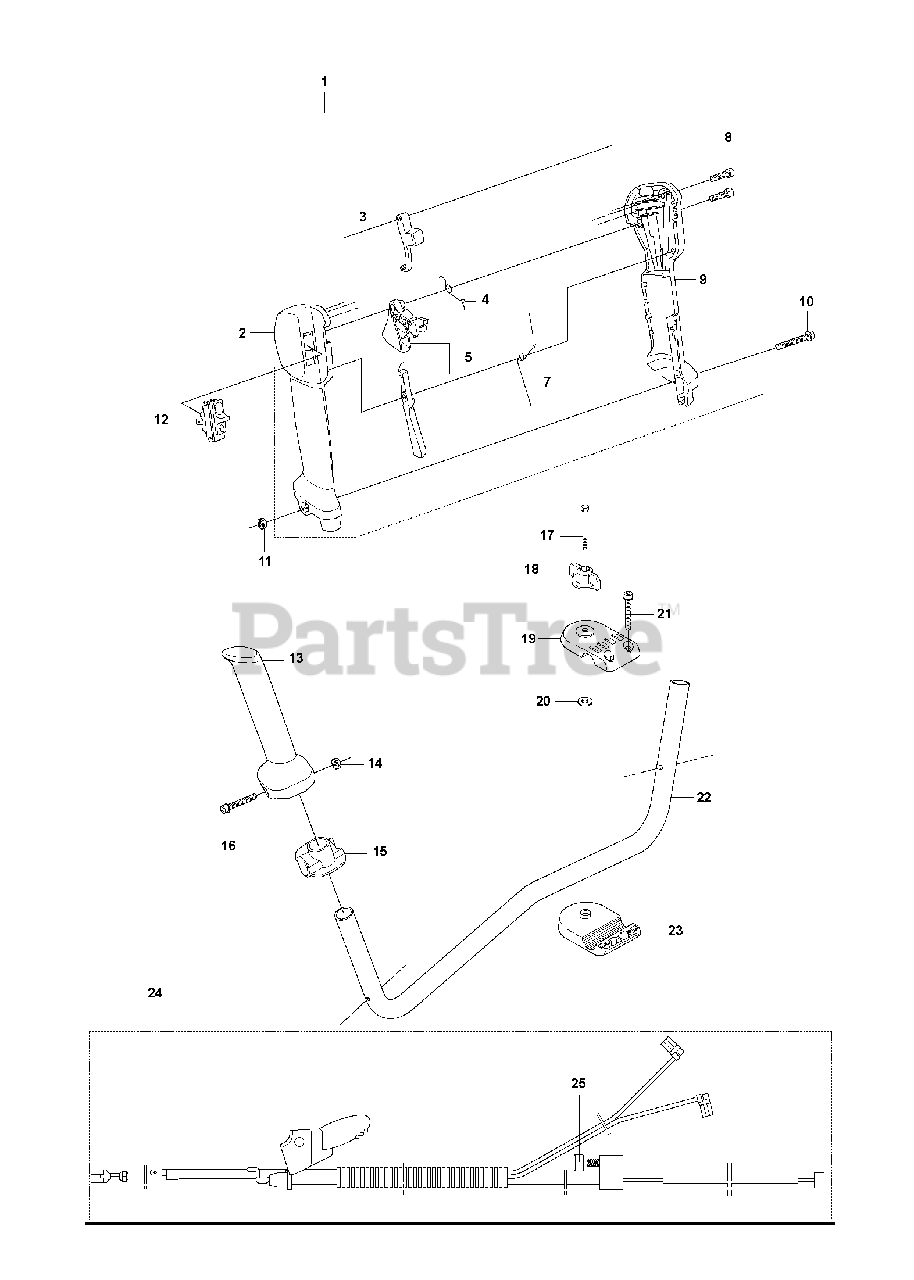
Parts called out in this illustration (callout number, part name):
1	THROTTLE HANDLE ASSY
3	SWITCH
4	SPRING
5	THROTTLE CONTROL
7	SPRING
8	SCREW
9	HANDLE HALF RIGHT
10	%SCREW
12	STOP BUTTON
14	NUT M6M M5
15	HANDLE FASTENER
17	%SCREW
19	HANDLE BRACKET
23	HANDLE BRACKET
24	WIRING ASSY
25	SCREW
